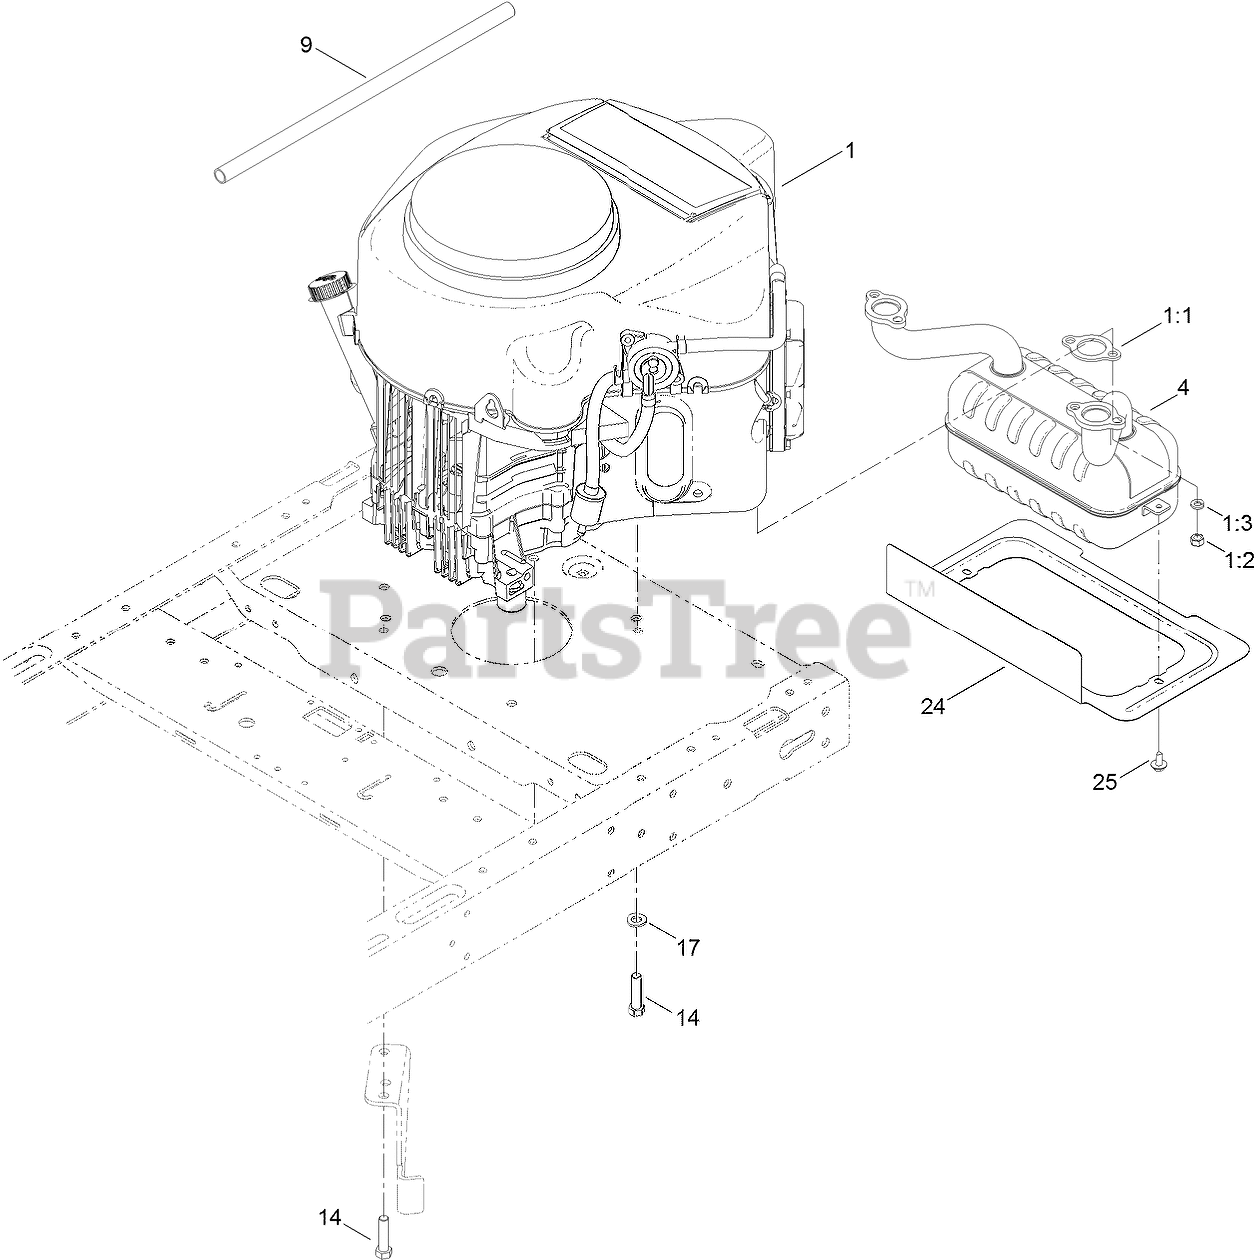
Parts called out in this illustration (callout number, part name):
1:1	GASKET-EXHAUST
1:3	WASHER-LOCK
4	MUFFLER-KAWASAKI
9	TUBE-DRAIN, OIL
14	BOLT-HH
17	WASHER-FLAT
24	SHIELD-HEAT
25	SCREW-HHFTF
